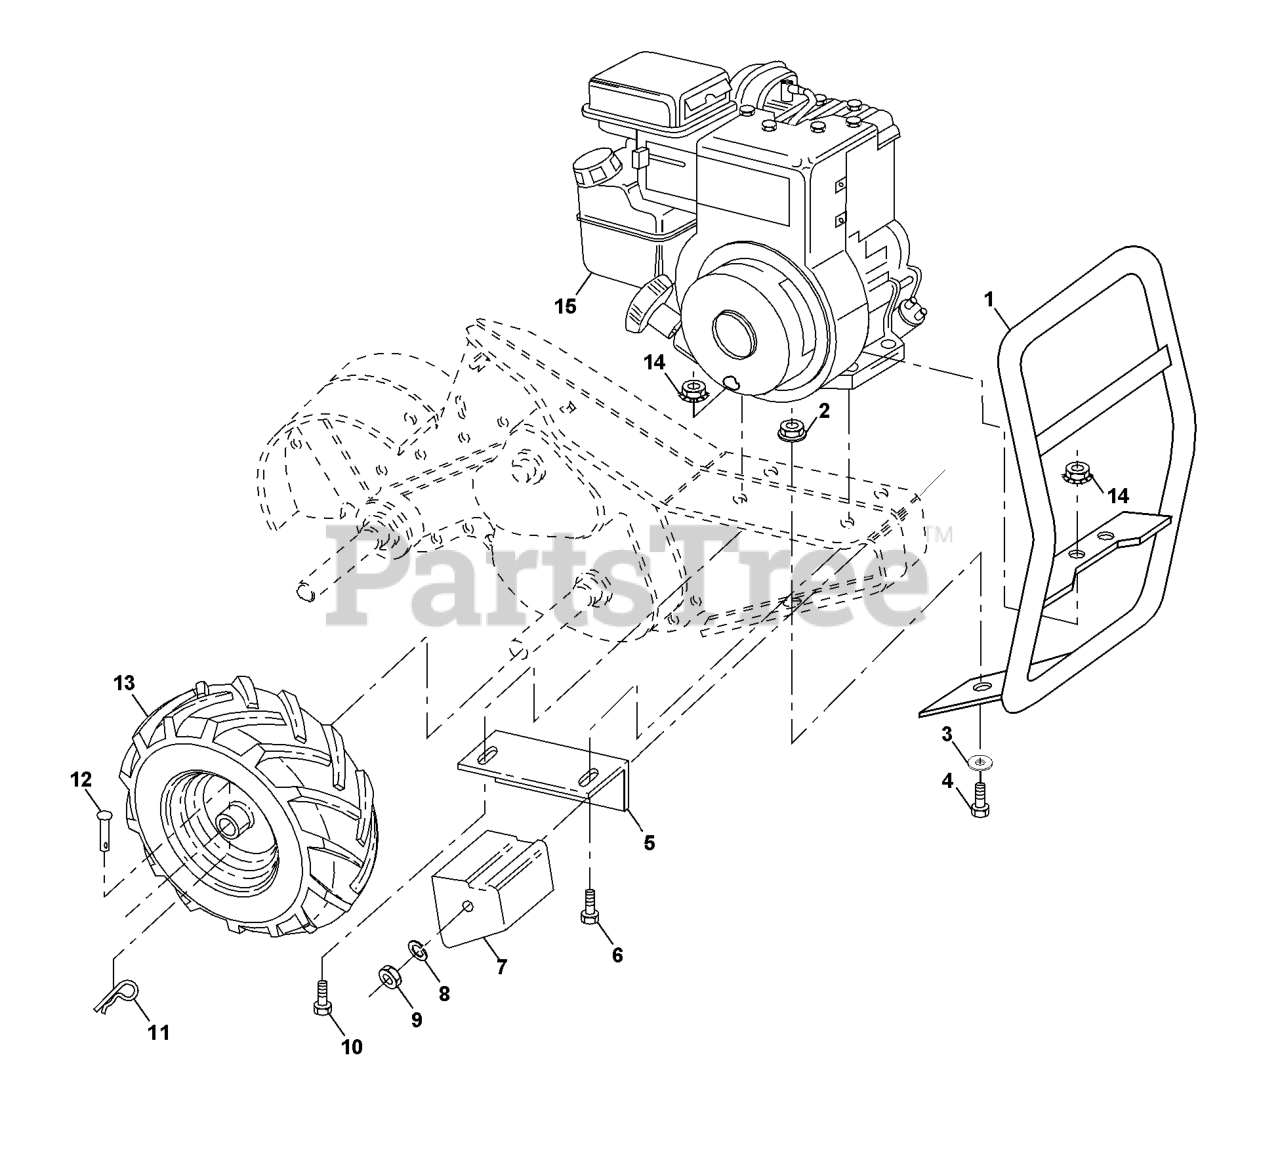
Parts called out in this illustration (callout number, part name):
1	BUMPER
2	LOCKNUT-FLANGE 5/16-18
3	WASHER
4	BOLT
5	DNO BRACKET RH CRT
6	Bolt, Hex 5/16-18 x 2
7	COUNTERWEIGHT, RH
8	WASHER, LOCK 3/8
9	NUT.HEX.3/8-16UNC
10	BOLT
11	RETAINER M
12	RIVET,DRILLED
13	TIRE.16X4-8.CHEVRON.TILLER
13	RIM
13	VALVE STEM LT
14	NUT
